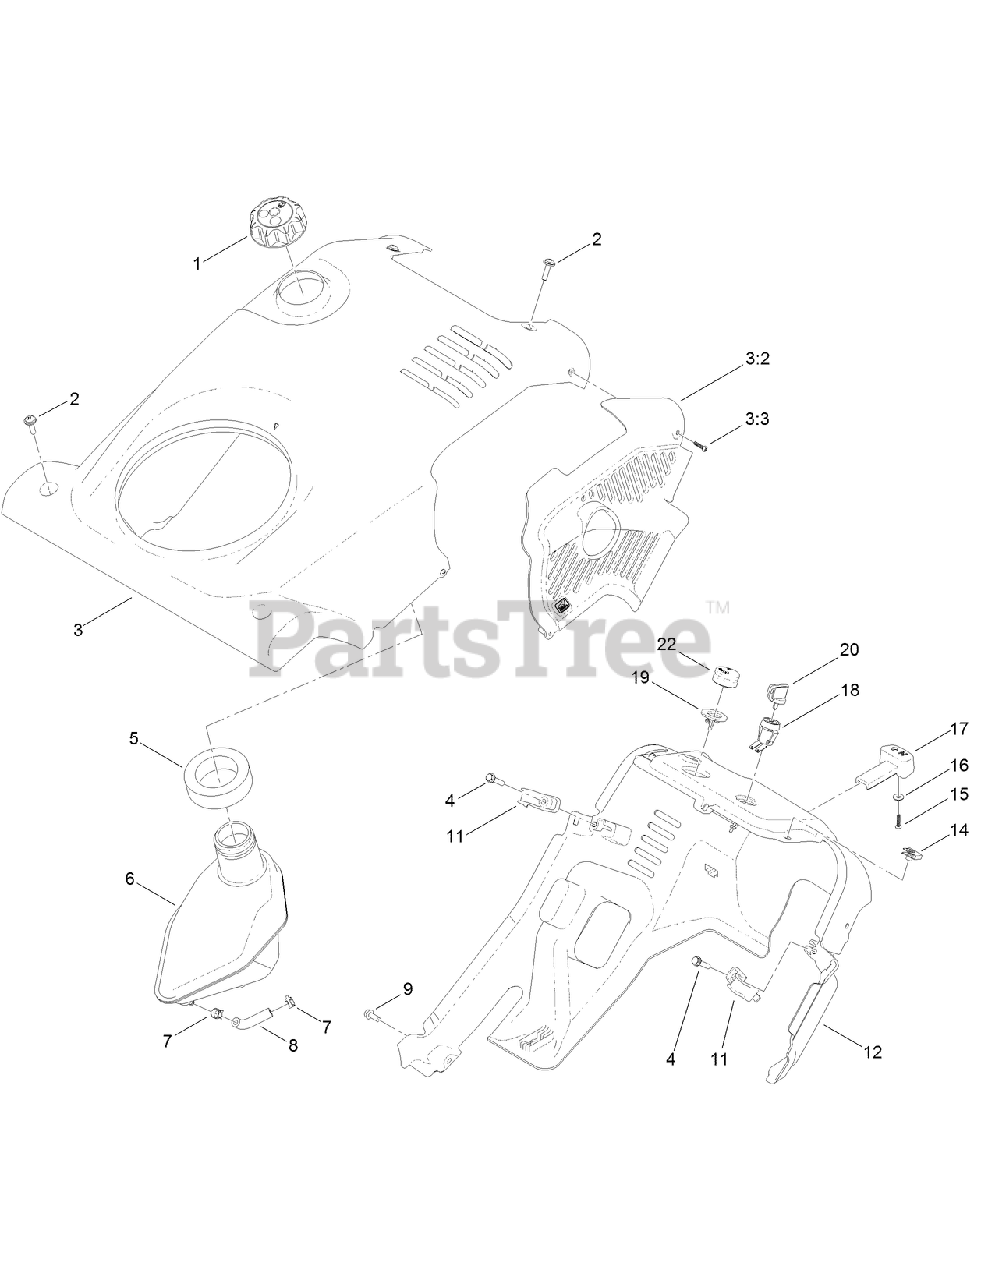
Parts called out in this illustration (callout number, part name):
1	CAP-GAS
2	SCREW-PPH
3	SHROUD ASM
3:2	BAFFLE-EXHAUST
3:3	SCREW-PPH
4	SCREW-PLASTITE
5	SEAL-TANK
6	TANK-FUEL, GAS
7	CLAMP-HOSE
8	HOSE-FUEL
9	SCREW-HWH
11	CLIP-SHROUD
12	SHROUD-LOWER
15	SCREW-PPH
16	WASHER-PLAIN
17	KNOB-CHOKE
18	SWITCH
19	BODY-PRIMER
20	KEY-IGNITION
22	BULB-PRIMER
